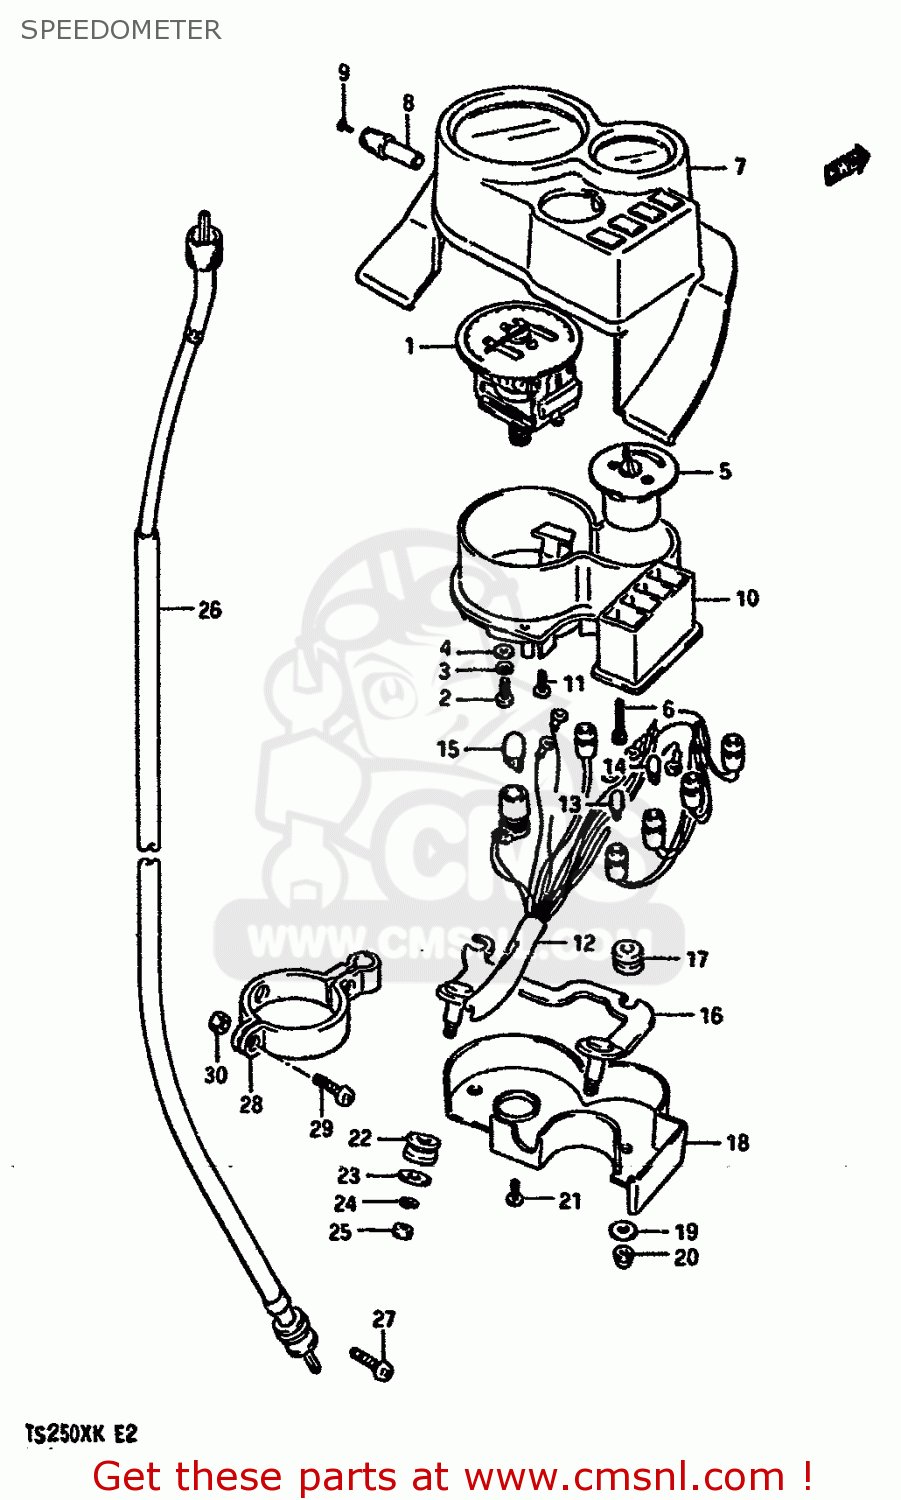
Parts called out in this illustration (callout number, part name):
1	SPEEDOMETER (KILO)
2	SCREW
3	LOCK WASHER
4	WASHER
5	TEMPERATURE METER
6	SCREW(3X22)
7	HOOD,METER
8	KNOB,TRIP
9	ROTOR,SPEED
10	CASE,METER
11	SCREW
12	SOCKET
13	BULB(12V3W,T6.5)
14	BULB(12V1.7W,T6.5)
15	BULB(12V3.4W,T10)
16	BRACKET,METER
17	CUSHION,METER
18	COVER,LOWER
19	WASHER,METER
20	NUT
21	SCREW
22	CUSHION
23	WASHER
24	WASHER,LOCK
25	NUT
26	CABLE ASSY,SPEEDOMETER
27	SCREW
28	CLAMP,METER CABLE
29	SCREW
30	NUT ,5MM
